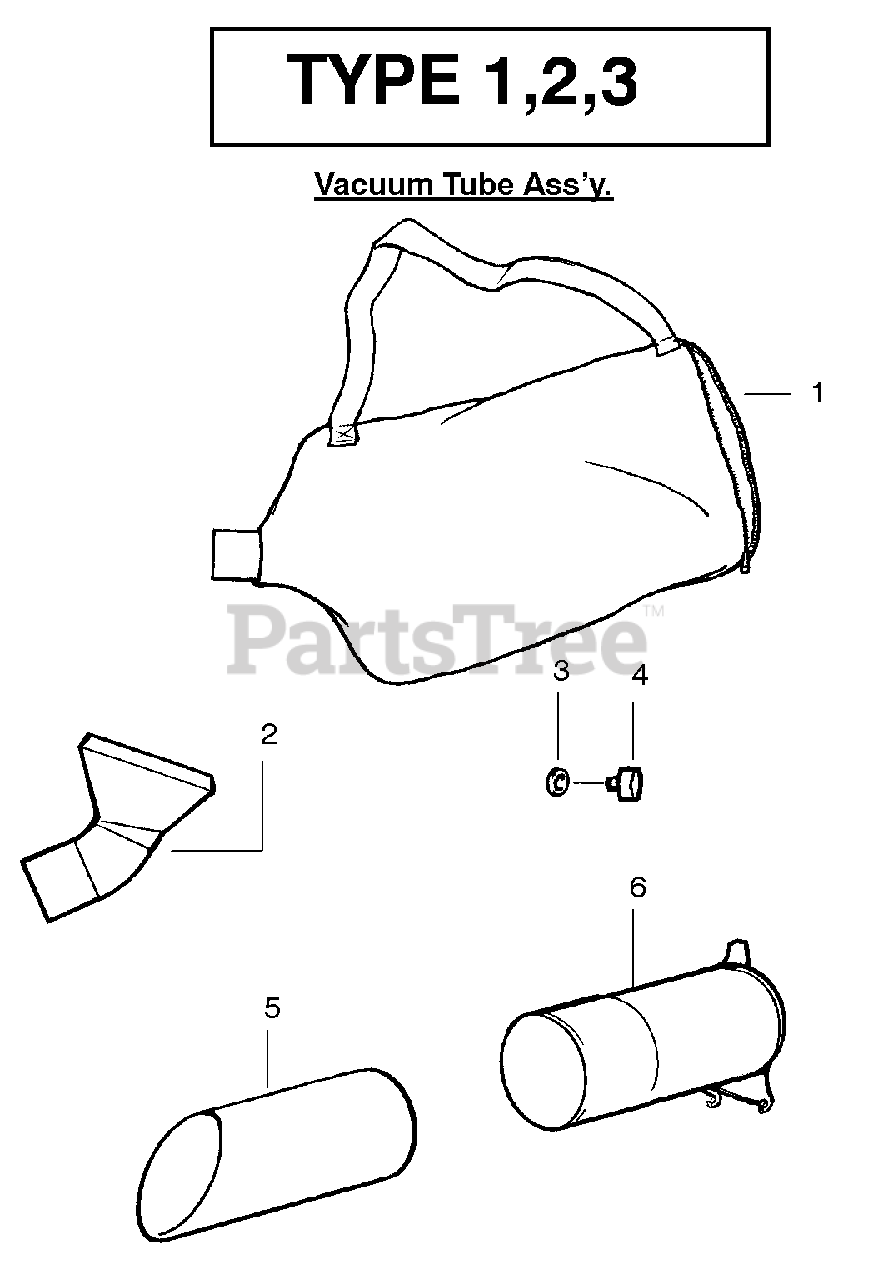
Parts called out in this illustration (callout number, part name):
1	Assy-Vac. Bag w/strap
2	Tube-Elbow Vac
3	Retainer-Vac Tube Knob
5	Tube-Lower Vac
6	Tube-Upper Vac
